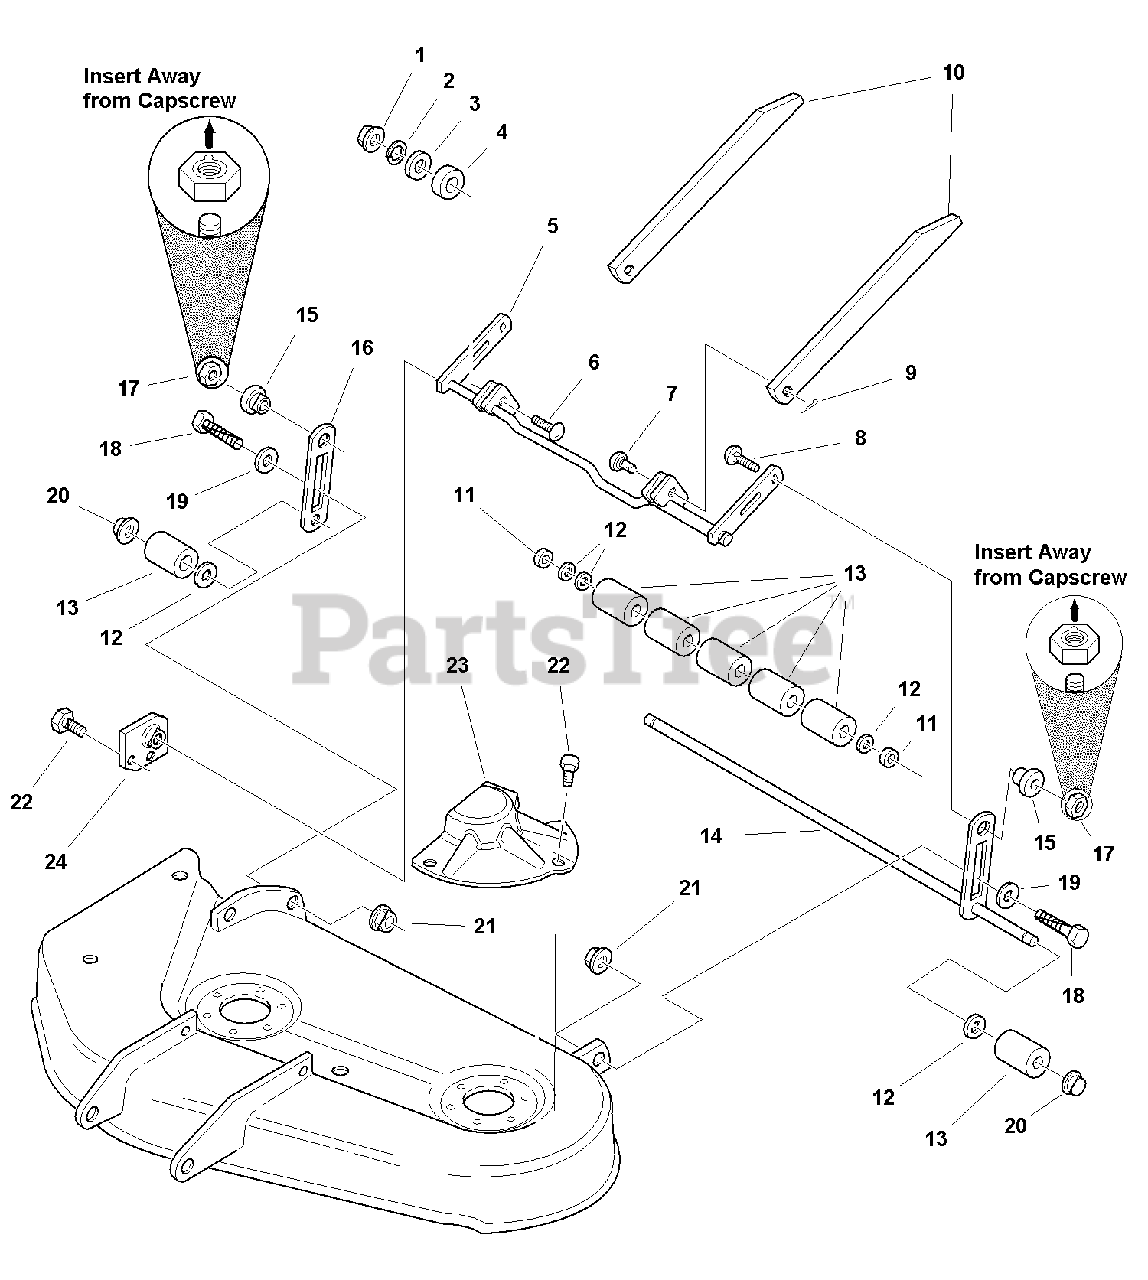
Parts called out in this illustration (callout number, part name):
1	NUT, Hex, 5/16-18
2	LOCKWASHER, 5/16
5	ARM ASSEMBLY
6	CARRIAGE BOLT, 5/16-18 x 1-1/4
7	PIN, Locking
8	CARRIAGE BOLT, 3/8-16 x 1-1/2
9	CLIP, Hair Pin
10	BAR, Mower Transport
11	SPACER, .66 ID
12	WASHER, 5/8
14	SHAFT ASSEMBLY, Roller (Includes Ref. 20)
15	NUT, Hex Adjusting, .99 DIA .687
16	PLATE, Support, RH
17	NUT, Hex Alum Lock, 3/8
18	BOLT, Shoulder, 3/8-16 X 1.34
19	WASHER, Flat, 1/2
20	NUT, Push
21	NUT, Flange Lock, 3/8
22	CAPSCREW, Taptite, 5/16-18 x 5/8
23	COVER, Arbor
24	PLATE, Support
